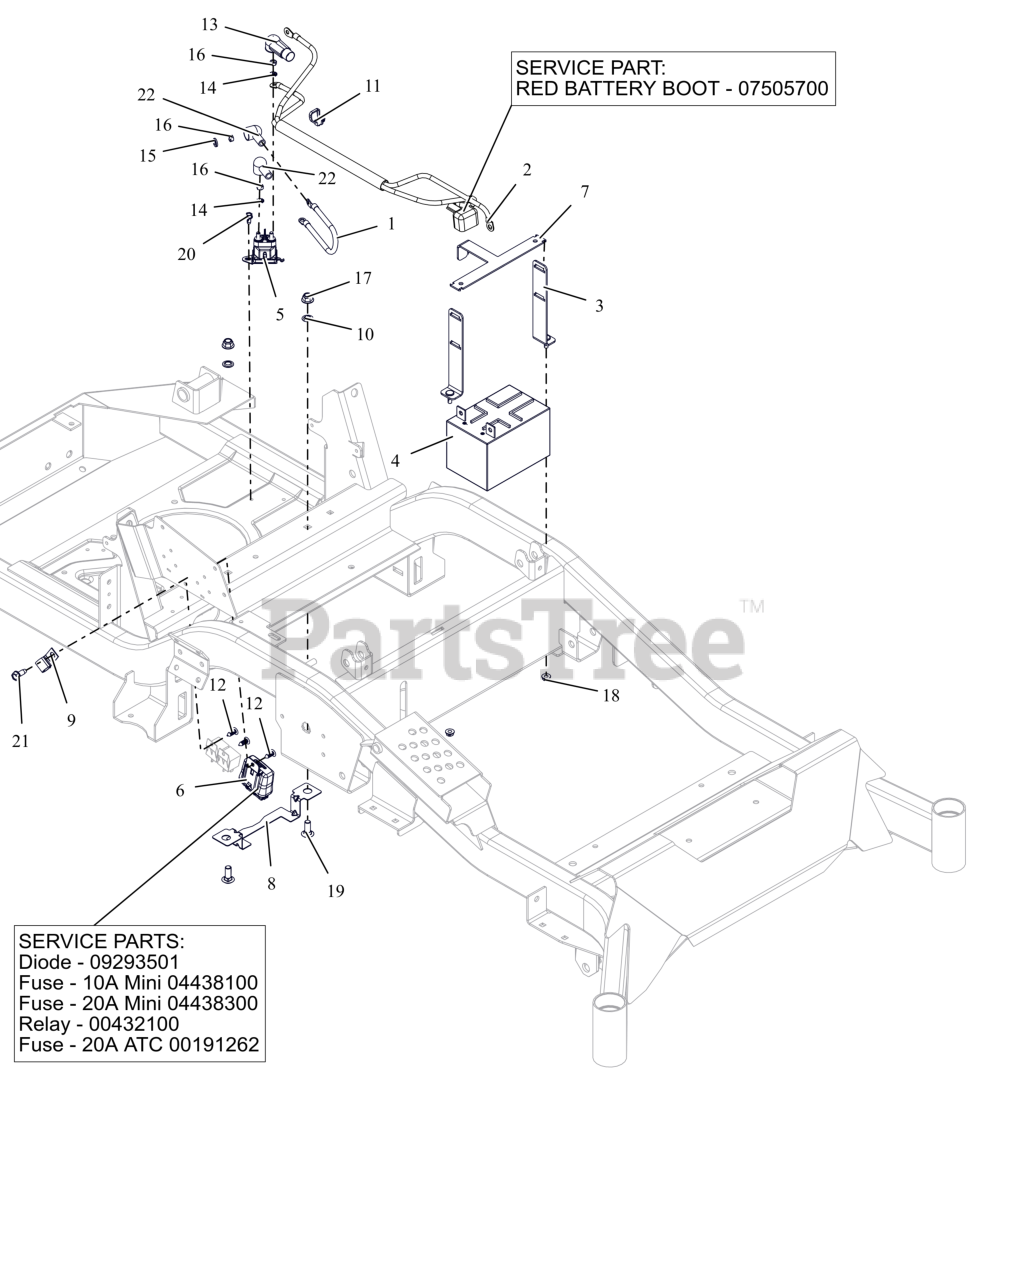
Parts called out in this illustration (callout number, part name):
1	CABLE, POS W/(2)1/4 RING 9.0LG
2	HARNESS, BATTERY HD
2	INSULATOR
3	WMT,BATTERY MOUNT HOLD DOWN
4	BATTERY, 12V 12A-190CCA
5	SOLENOID, STARTER (SEALED)
6	HARNESS, WIRE
6	DIODE, CONNECTOR SHELL
6	FUSE,10 AMP MINI-ATC
6	FUSE,20 AMP MINI ATC
6	RELAY,SEALED W/DIODE
6	FUSE, 20 AMP BLADE S/O
7	BRKT, BATTERY TIE DOWN
8	GUARD, ELECTRICAL HARNESS
9	J-CLAMP
10	NUT-PUSH .38 DIA. PAL ZINC
11	CABLE TIE W/ TREE (.25 HOLE)
12	RIVET, .25 NYLON PANEL
13	BOOT, .65ID POS
14	WSHR,LK-EXT.262X.502X.026 ZCC
15	WSHR,LK-REG .312X.078 ZCC
16	NUT-STD M6-1.0 ZCC
17	NUT,NYL-FLG .38-16 GF ZCC
18	NUT-LK-TOP-FLG .250-20 GF ZCC
19	BLT, RHSN .38-16X1.00 G5 ZCC
20	SCR-TAP .25-20X.50 HWH ZCC
21	SCR,TAP .312-18X.75 HWH TR ZCC
22	BOOT, EYELET TERMINAL
